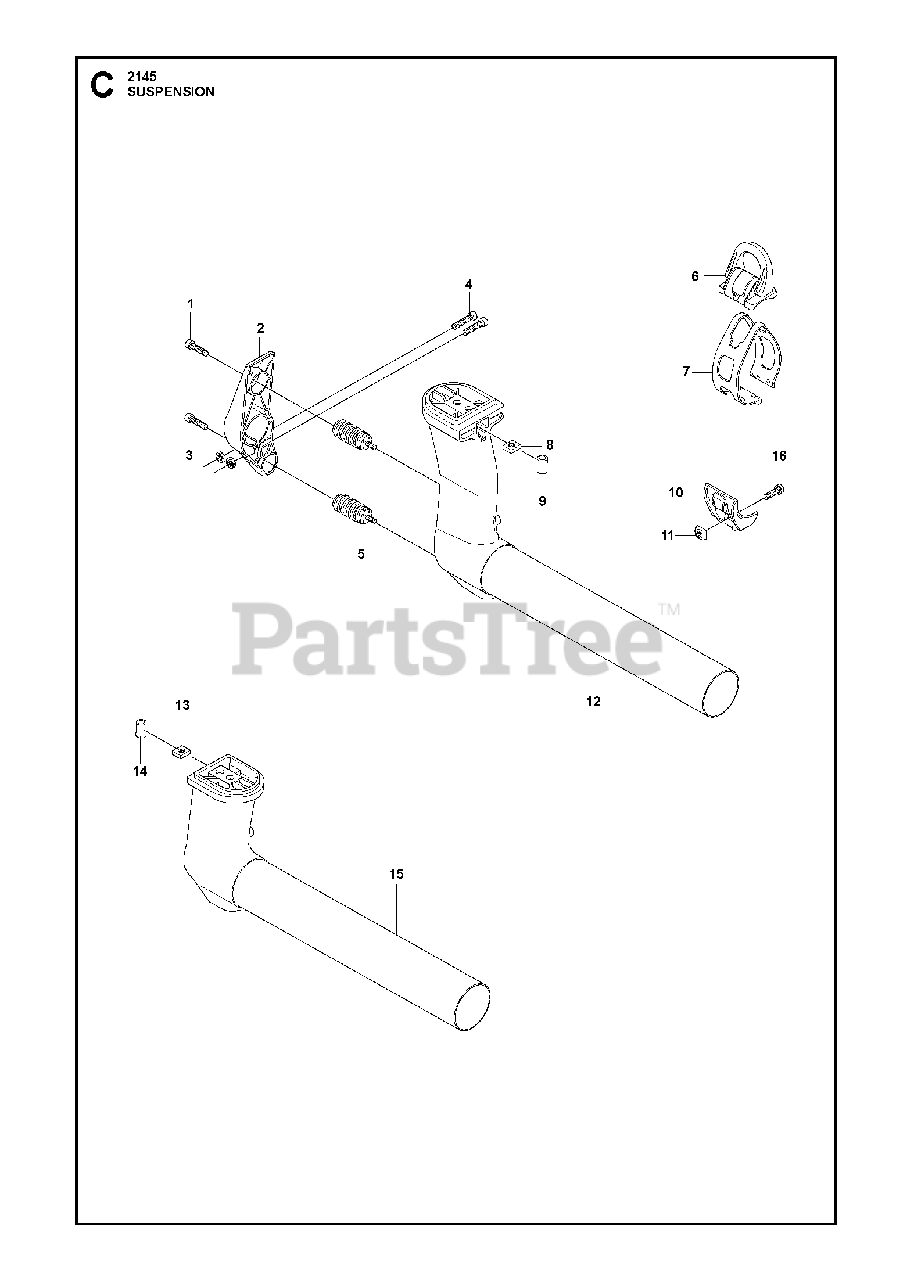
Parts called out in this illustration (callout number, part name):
6	HARNESS HANGER LOOP
10	BRACKET, LOWER HANGER
11	SQUARE NUT M5
